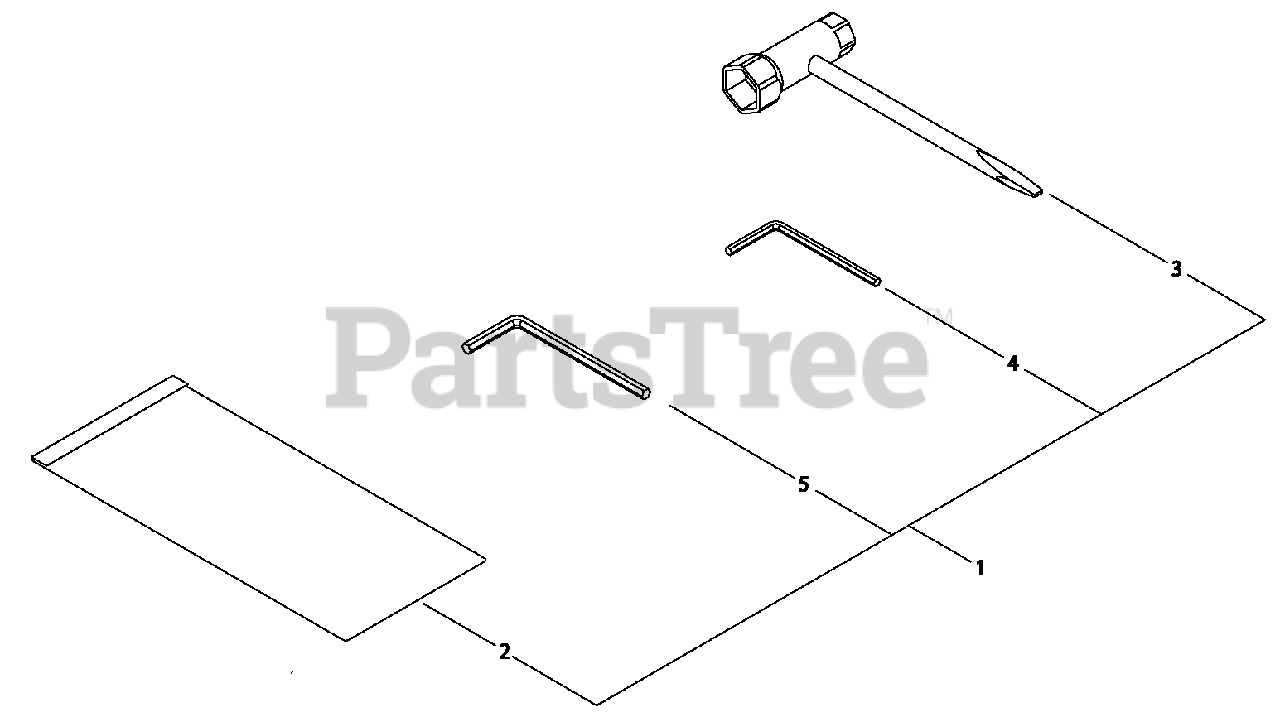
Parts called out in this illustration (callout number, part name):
1	TOOL KIT, SERVICE
2	T-WRENCH 17×19 MM
3	WRENCH, ALLEN 4 MM
4	WRENCH, ALLEN 5 MM
5	BAG, TOOL
